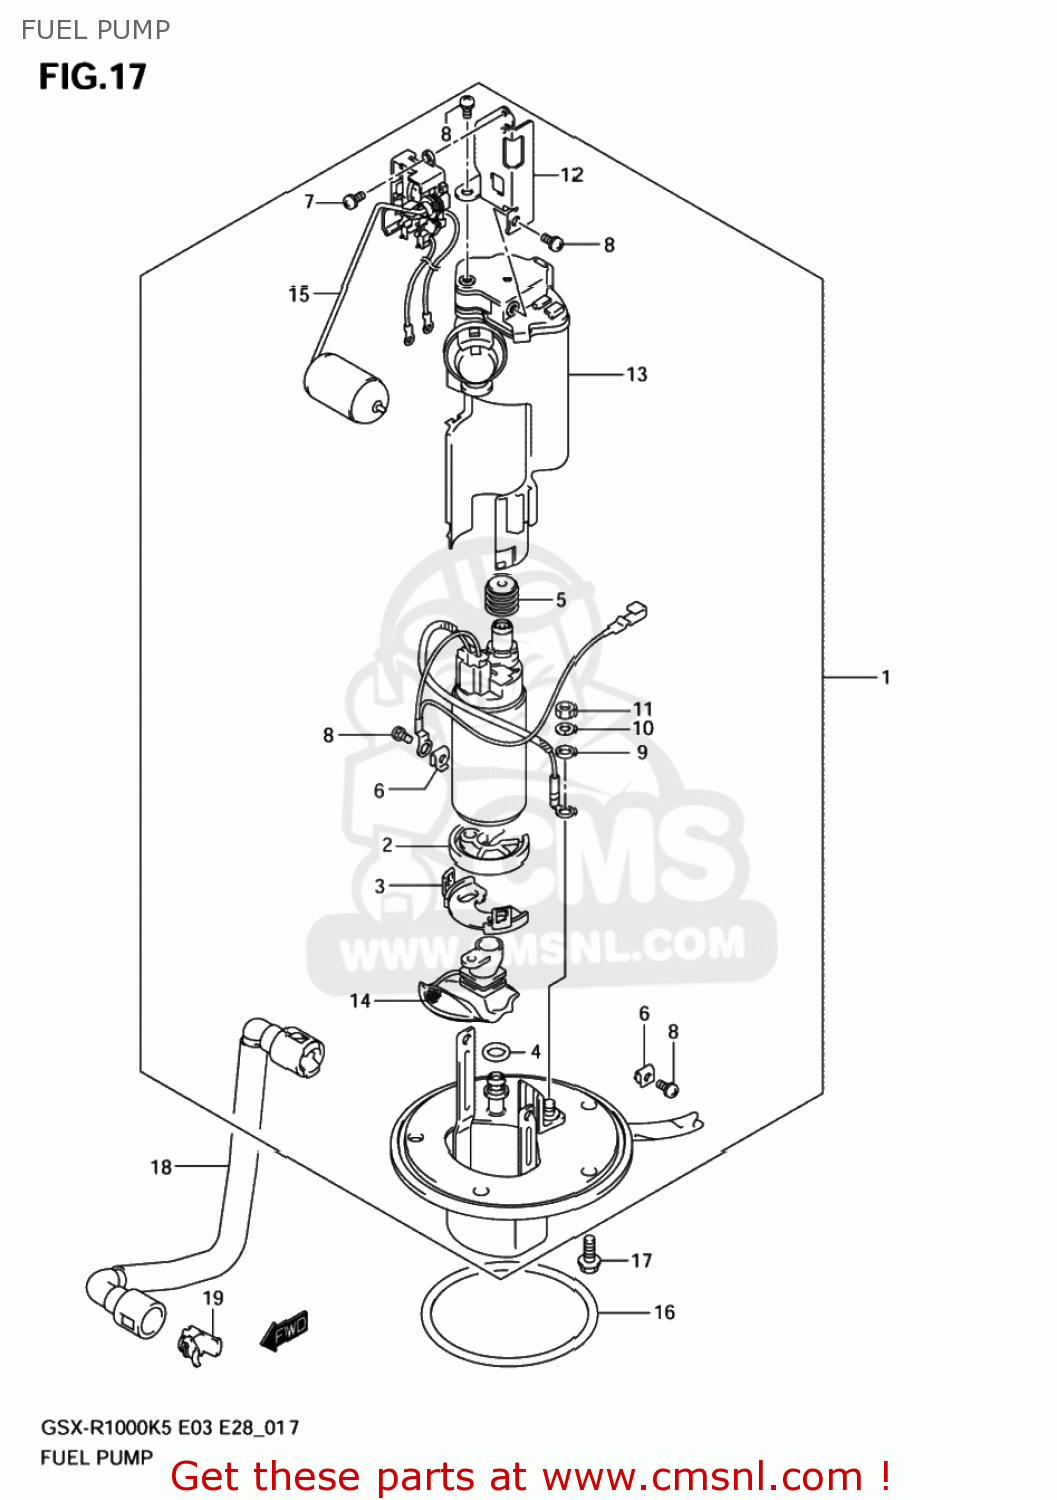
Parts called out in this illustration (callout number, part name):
1	PUMP ASSY,FUEL
2	CUSHION
3	HOLDER,FUEL PUMP
4	O RING
5	BUSH,FUEL PUMP
6	NUT
7	SCREW
8	SCREW
9	WASHER
10	WASHER,SPRING
11	NUT
12	BRACKET,FUEL GAUGE
13	FILTER,FUEL
14	STRAINER,FUEL PUMP
15	GAUGE ASSY,FUEL LEVEL
16	O RING,FUEL PUMP
17	BOLT
18	HOSE,FUEL
19	RETAINER
